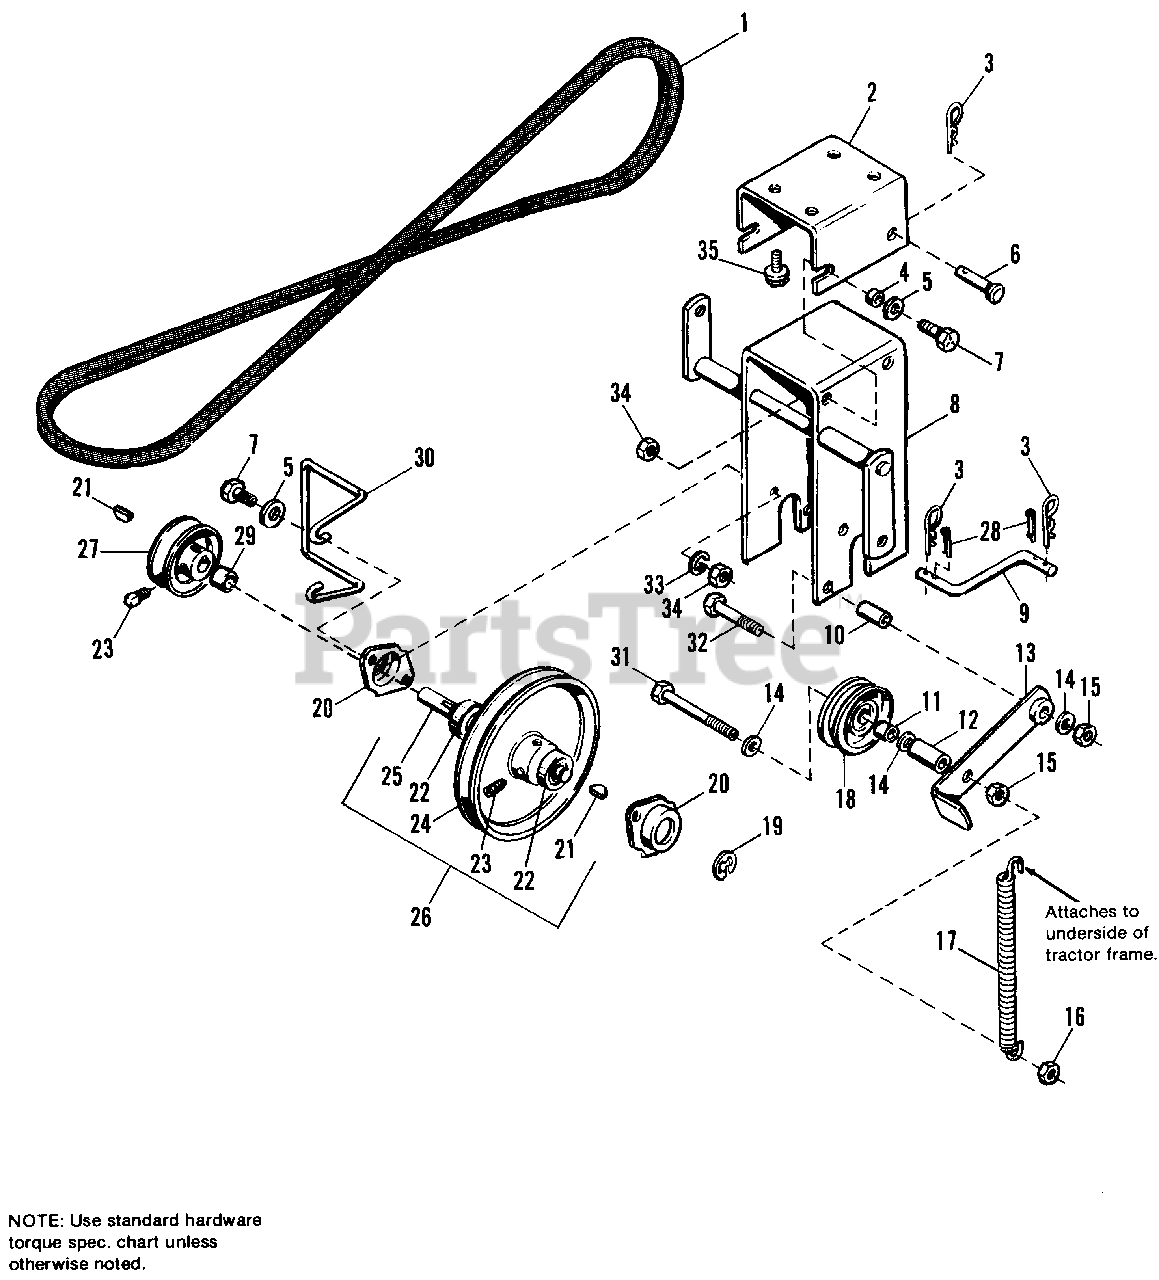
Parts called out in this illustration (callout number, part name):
1	BELT, "V" Front
2	BRACKET, Jackshaft, Frame
3	PIN
5	WASHER, Flat, 3/8 x 7/8 x 1/16
6	PIN, Rivet
7	BOLT, Hd., 5/16-18 x 1
8	BRACKET ASSY., Jackshaft
9	LINK, Clutch
13	ARM, Idler Assy.
14	WASHER, Flat, 3/32 x 1 x 16
15	NUT, Hex, 3/8-16 Unc.
16	NUT, Hex, 3/8-16 Unc.
17	SPRING, Extension
18	PULLEY ASSY.
19	"E" RING
20	RETAINER, Bearing
21	KEY, Woodruff, #9, 5/16 x 3/4
23	SETSCREW, 5/16-18 x 3/8
24	PULLEY ASSY.
25	SHAFT, Jack
26	SHAFT ASSY., Jack
28	COTTER PIN
30	STOP, Belt
31	BOLT, Hex Hd., 3/8-16 Unc. x 3
32	BOLT, Hex Hd., 3/8-16 Unc. x 1-1/2
33	LOCKWASHER, 5/16
34	NUT, Hex, 5/16-18
35	SCREW, Hex, Washer Hd., Taptite, 3/8-16 x 3/4
